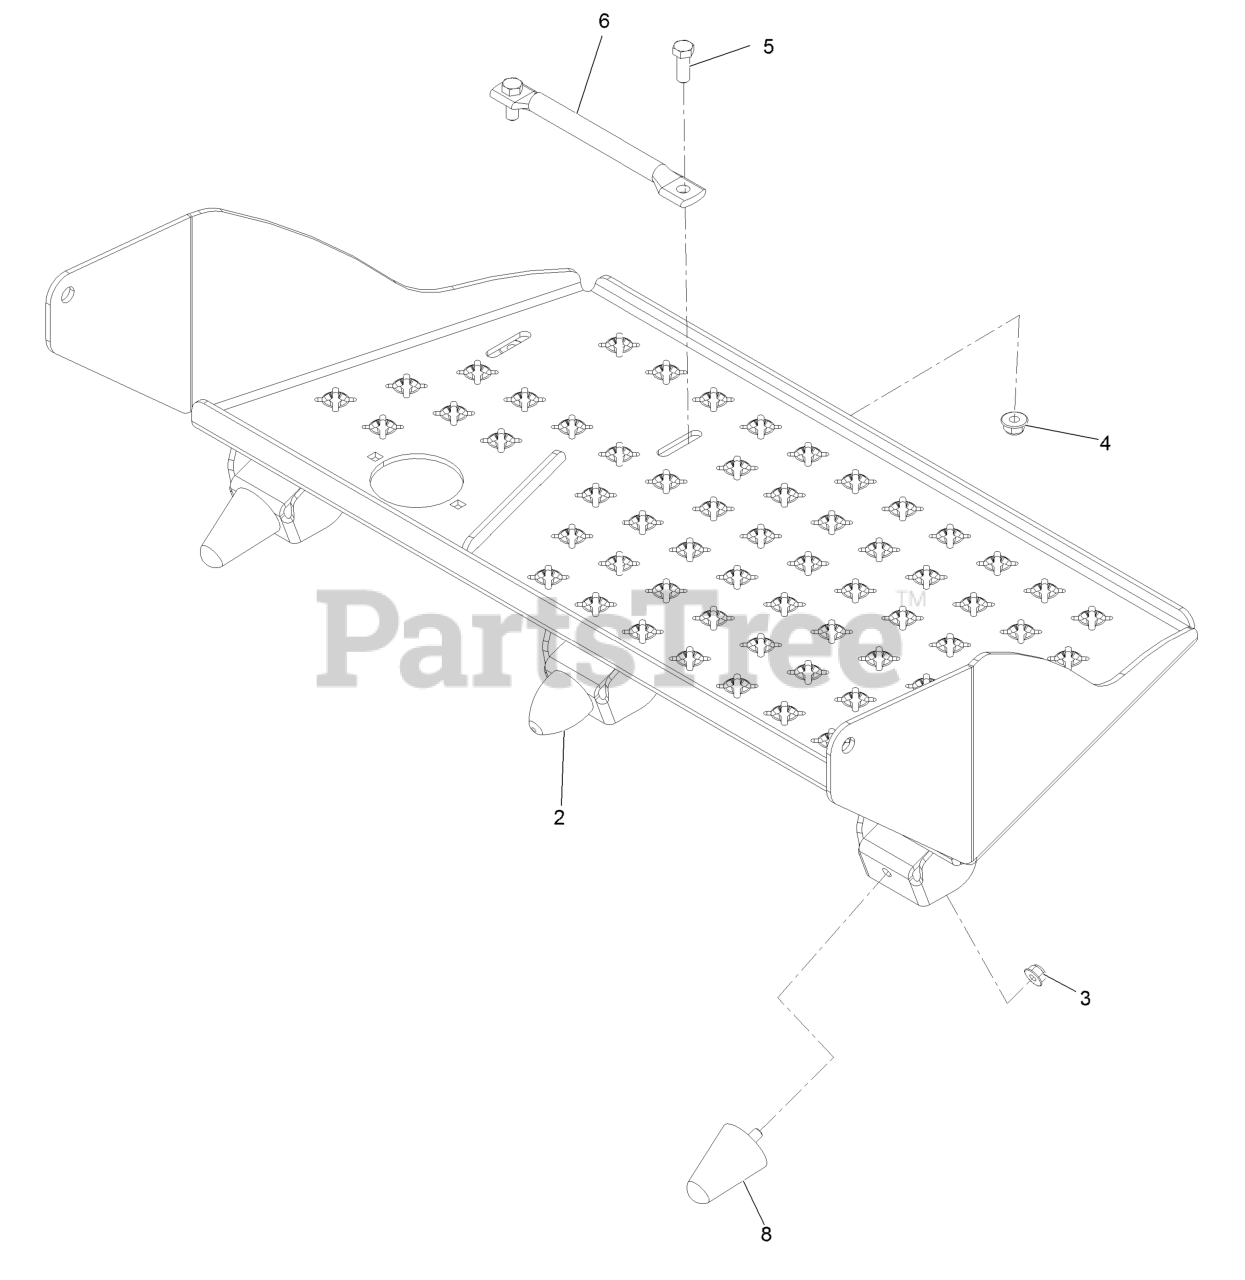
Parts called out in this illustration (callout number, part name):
2	BUMPER-RUBBER
3	NUT-HF, NI
4	NUT-HF, NI
5	SCREW-HH
6	ROCKER-FOOT PEDAL
8	BUMPER-RUBBER
